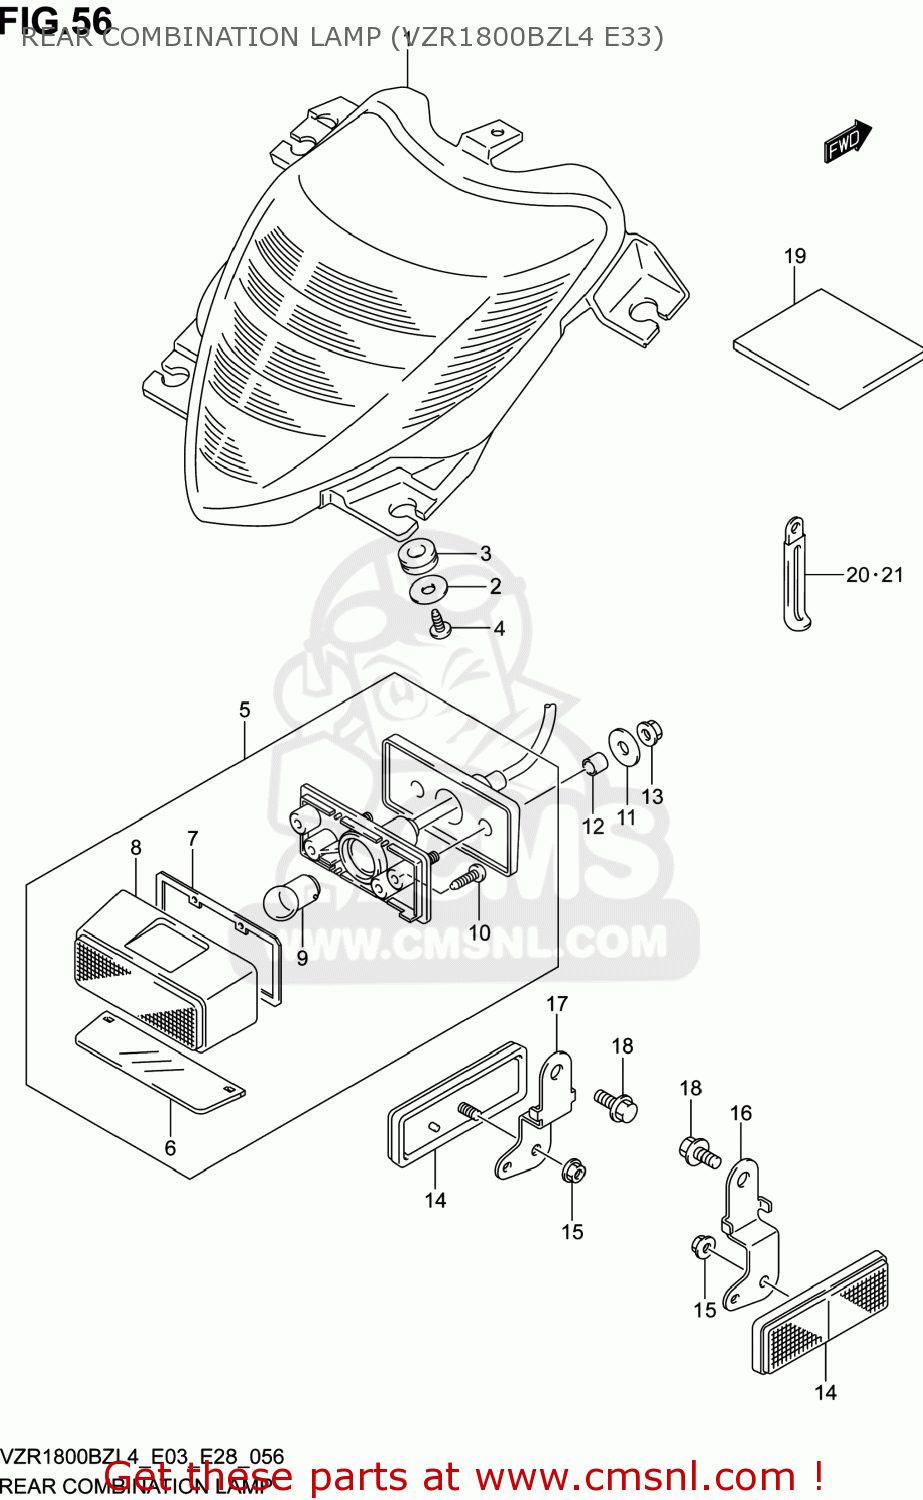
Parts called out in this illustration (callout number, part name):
1	LAMP ASSY,RR COMBINATION
2	WASHER(5.5X20X1.2)
3	CUSHION
4	SCREW
5	LAMP ASSY,LICENSE
6	LENS,LICENSE LAMP
7	GASKET (NAS)
8	COVER,LICENSE LAMP
9	BULB(12V5W,BF150-40160A)
10	SCREW
11	WASHER(6.5X20X1.2)
12	SPACER(6.5X9X8)
13	NUT
14	REFLECTOR ASSY,RR
15	NUT
16	BRACKET,RR SIDE RR,R
17	BRACKET,RR SIDE RR,L
18	SCREW
19	CUSHION,HELMET BOX
20	CLAMP(L:45)
21	CLAMP(L:45)
